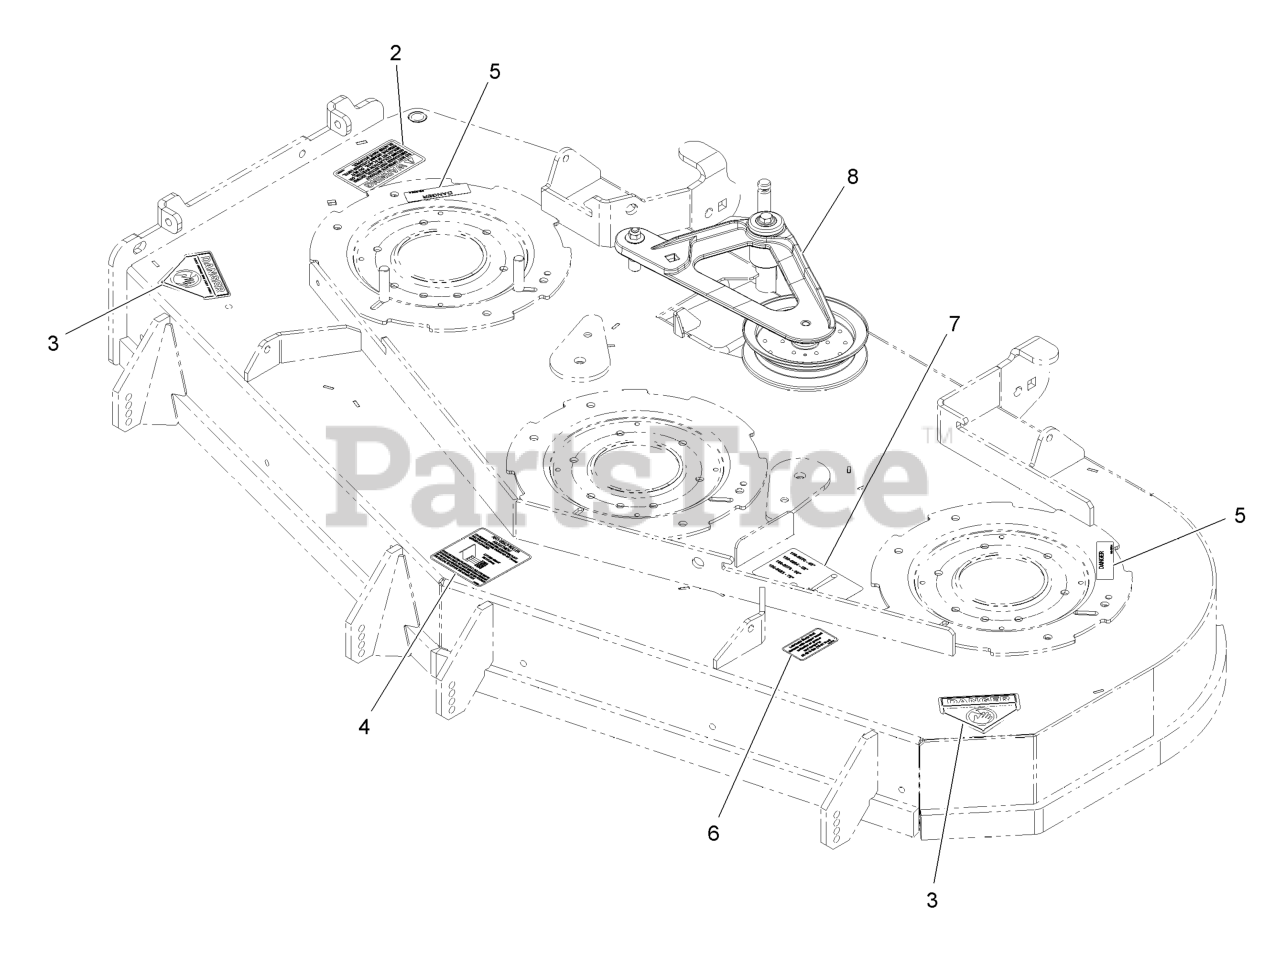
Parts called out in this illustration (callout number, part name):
2	DECAL-WARNING, DISCHARGE
3	DECAL-DANGER
4	DECAL,ANTISCALP
5	DECAL-COVER, MISSING
6	DECAL,BOLT TORQUE
7	DECAL,BELT ROUTING
8	DECK IDLER ASM
